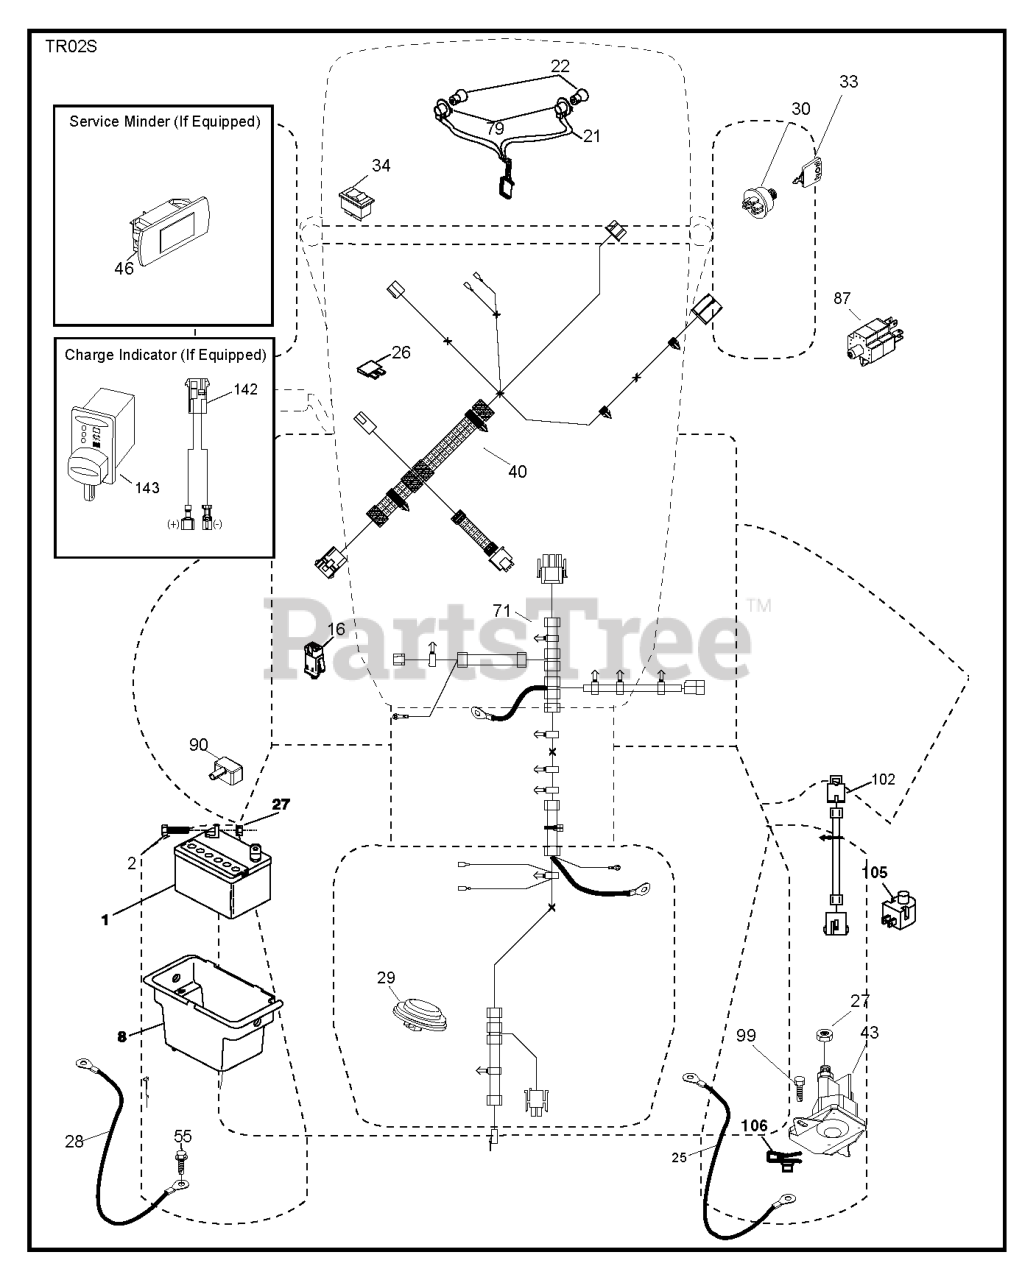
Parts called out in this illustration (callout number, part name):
1	REPL BY 532 12 38-99
2	Bolt, Hex Hed. 1/4-20 UNC x 3/4 (AYP part number)
8	BOX.BATTERY.MNT.REAR.L
16	SWITCH INTERLOOK PUSH-IN
21	HARNESS.LIGHT W/4152J BULBS
22	Bulb Light #1156 (AYP part number)
25	CABLE.BATT.RED.8GA.17
26	FUSE 20AMP
27	Nut Keps Hex 1/4 - 20 UNC (AYP part number)
28	CABLE.GROUND.REAR.BATTERY.8G
29	SWITCH.SEAT.DELTA.OPC.
30	SWITCH.IGN.DELTA.W.LGH.ROS
33	KEY.CHAIN.BLISTER.PACK.GEN.USA
34	Switch Light Blk Blk Red (AYP part number)
40	HARNESS.TEX.DASH.MAN.REAR BATT
43	SOLENOID.STARTER.BRASS.PLUNGER
55	SCREW 5/16"
71	HARNESS.CHASSIS.RRBATT.RDYSTRT
79	BULB HOLDER ASM.
87	SWITCH.INTRLCK.CLUTCH.
90	COVER.TERMINAL.BATTERY
99	SCREW HEXWSHR 1/4-20X3/4
102	HARNESS PIGTAIL PCH TEX ROS
105	REVERSE SWITCH
106	1/4-20 U NUT
